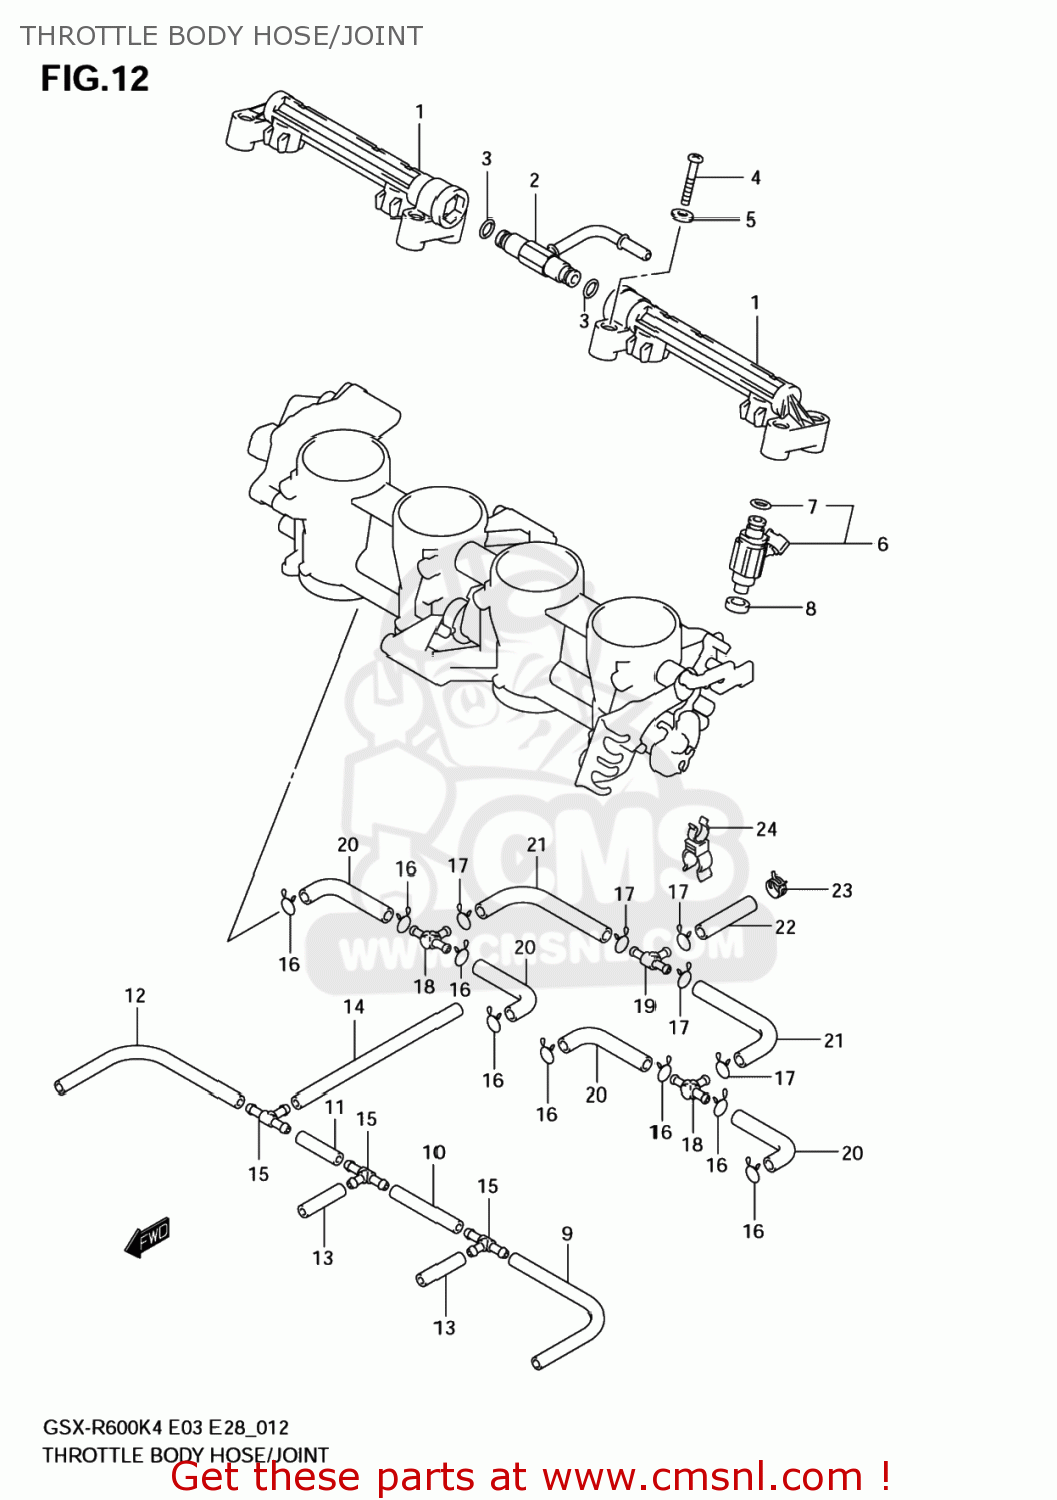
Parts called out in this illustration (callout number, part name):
1	DELIVERY PIPE
2	NIPPLE ASSY
3	O RING
4	SCREW
5	PACKING (NAS)
6	INJECTOR ASSY
7	O RING
8	SEAL
9	HOSE(3.2X7.4X225)
10	HOSE(3.2X7.4X225)
11	HOSE(3.2X7.4X225)
12	HOSE(3.2X7.4X225)
13	HOSE(3.2X7.4X225)
14	HOSE(3.2X7.4X225)
15	3WAY,VACUUM HOSE
16	CLIP
17	CLIP
18	NIPPLE
19	NIPPLE
20	HOSE
21	HOSE
22	HOSE
23	CLIP
24	CLAMP
